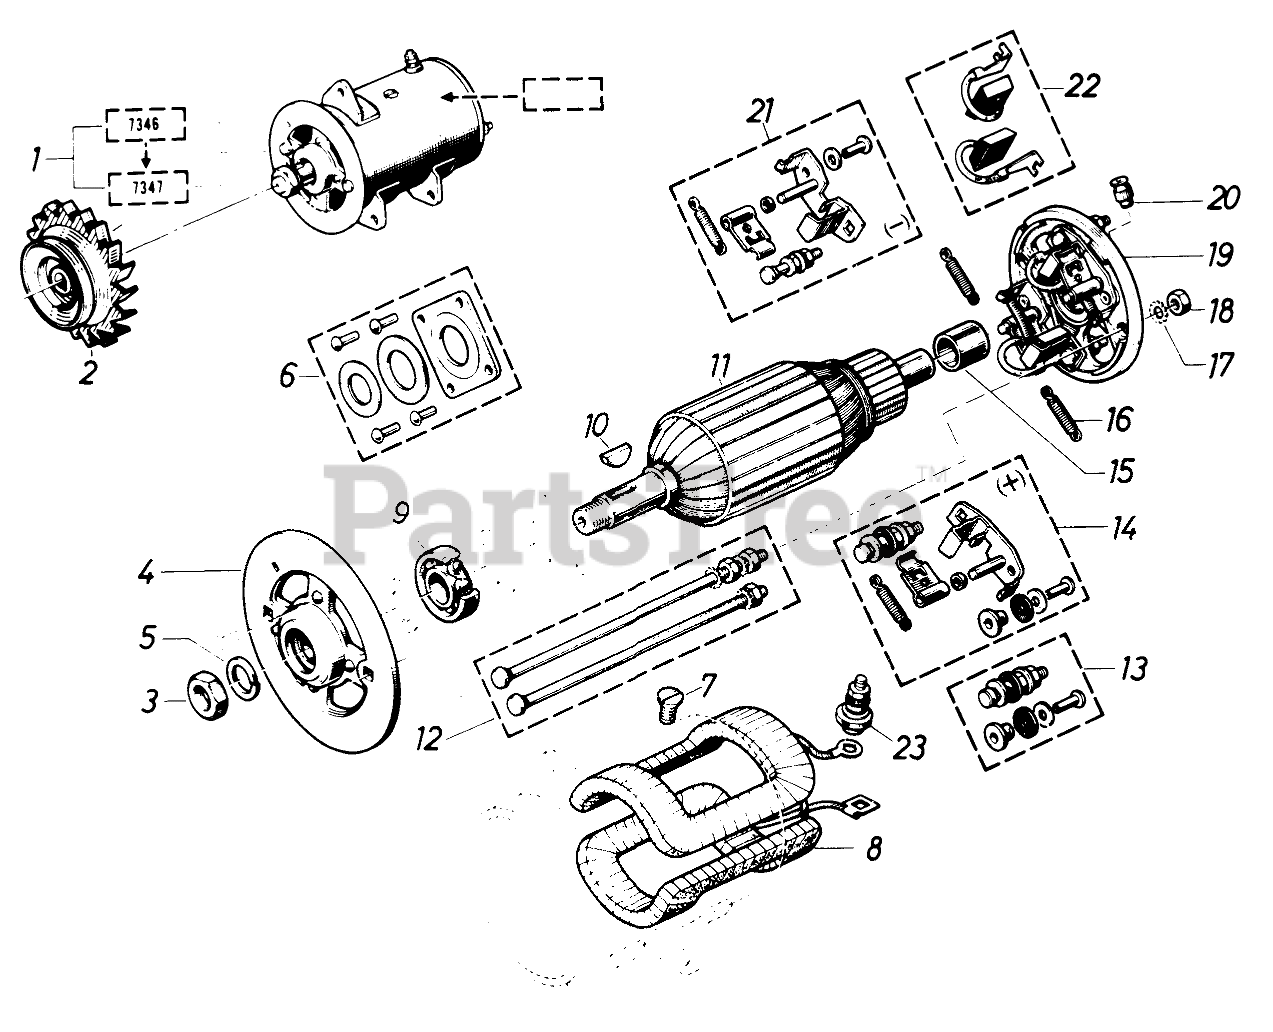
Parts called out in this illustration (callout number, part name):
1	Generator
2	Fan and Pulley Assy
4	Bearing Plate
5	Spring Washer
6	Set of Repair Spare Parts
7	Screw
8	Field Winding
9	Ball Bearing
11	Armature
12	Screw Set
13	Clamp
14	Brush Parts Set
15	Bushing
16	Spring
17	Lock Washer
19	Commutator End Plate Assy.
20	Nipple
21	Brush Parts Set
22	Brush Set
23	Clamp
